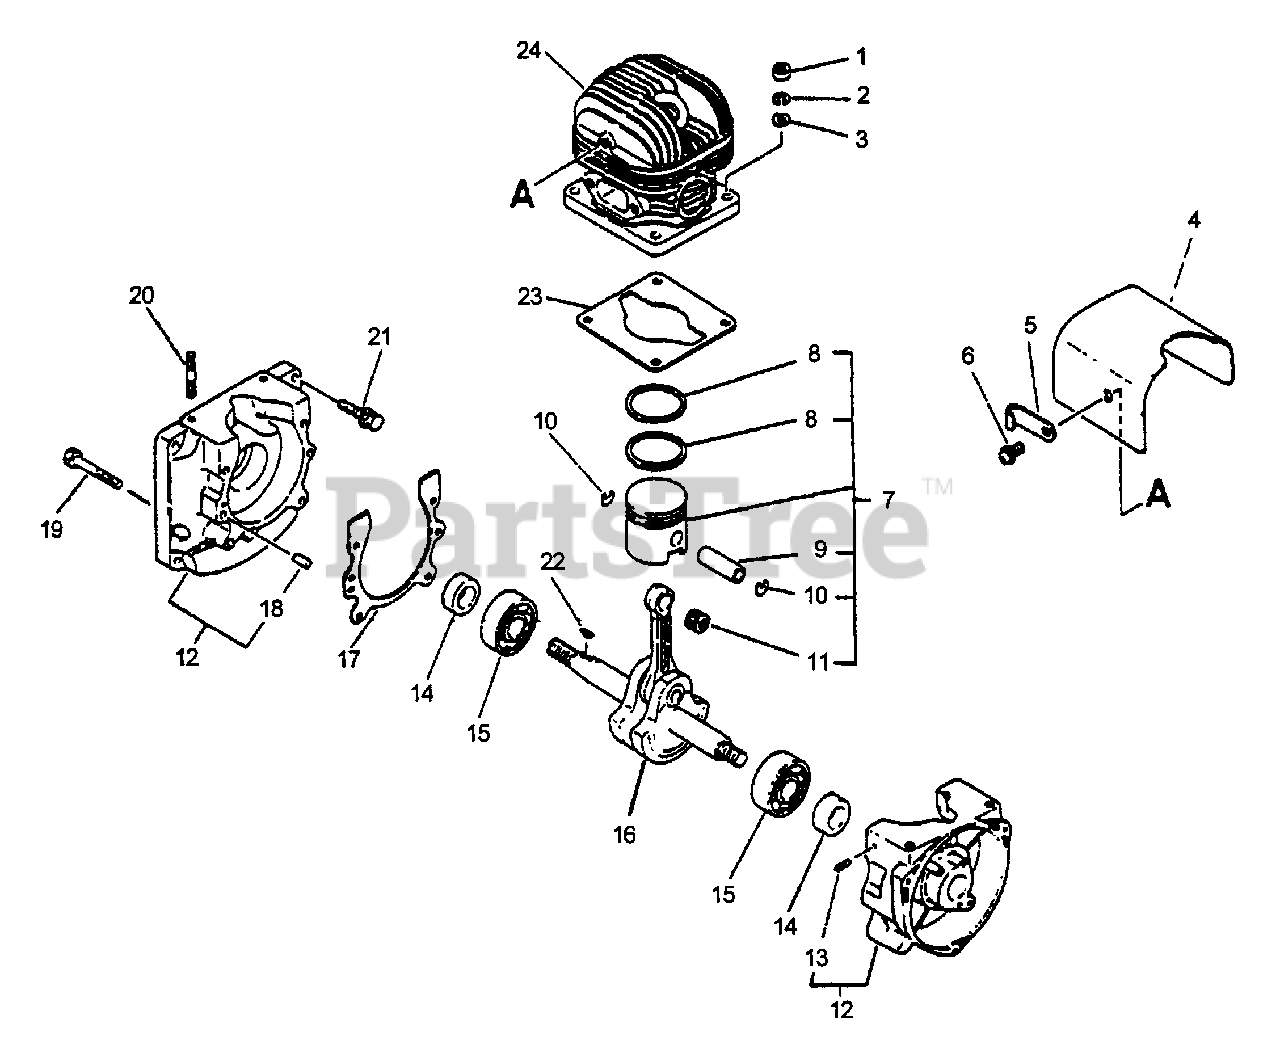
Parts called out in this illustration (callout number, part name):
1	NUT, HEX M6
2	WASHER, SPRING 6
3	WASHER, FLAT 5.5×10×0.8
4	COVER, CYLINDER
5	CLIP, CORD
6	BOLT 6×10
7	PISTON KIT
8	RING, PISTON
9	PIN, PISTON
10	RING, SNAP 8
11	BEARING, NEEDLE
12	CRANKCASE KIT
13	CONNECTOR
14	SEAL, OIL
15	BEARING, BALL 6202
16	CRANKSHAFT ASSY
17	GASKET, CRANKCASE
18	PIN, LOCATING 5×10
21	BOLT - 5×25
23	GASKET, CYLINDER
24	CYLINDER
